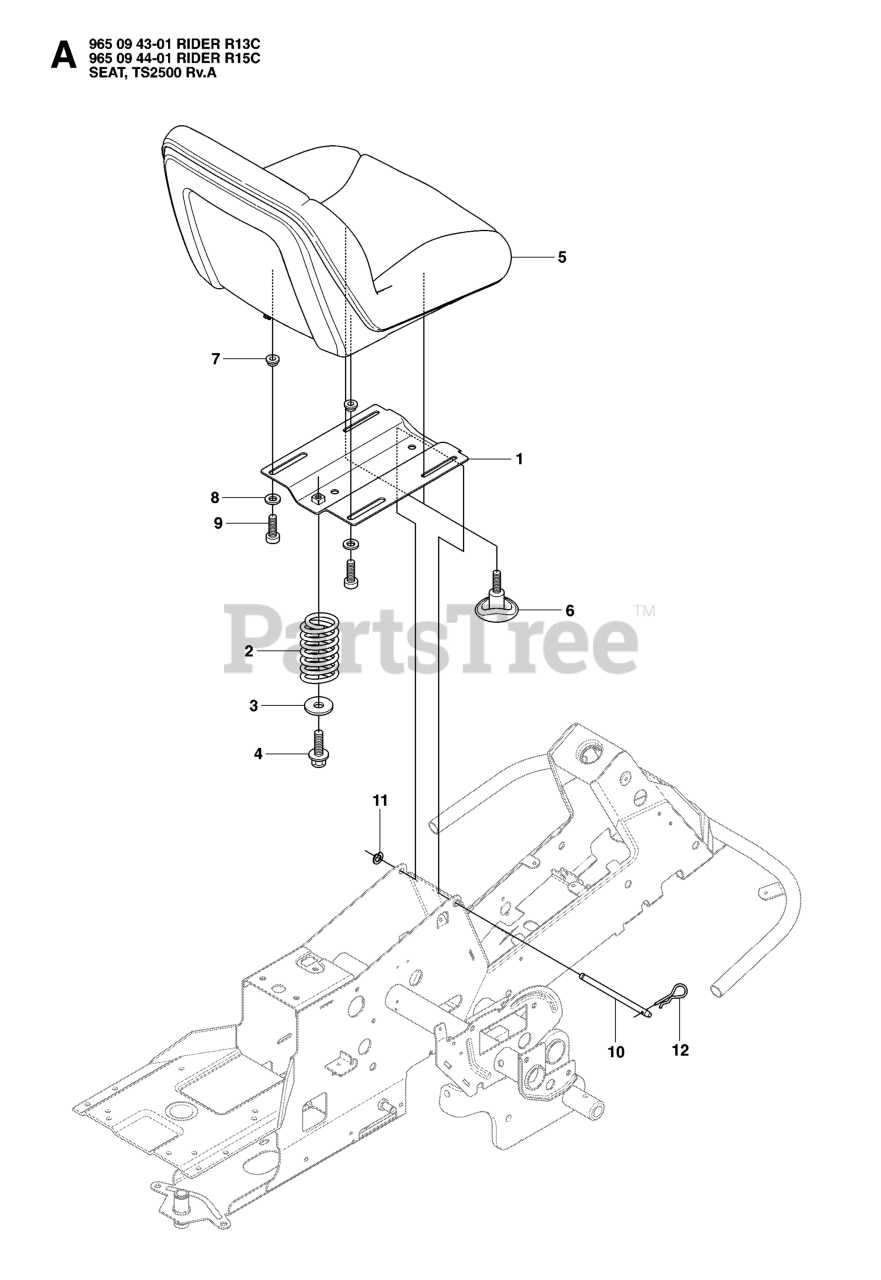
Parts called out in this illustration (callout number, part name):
1	SEAT BRACKET
2	SEAT SPRING
4	Screw M10x25
5	SEAT
6	ADJUSTING KNOB
11	RETAINING RING SGA 10
